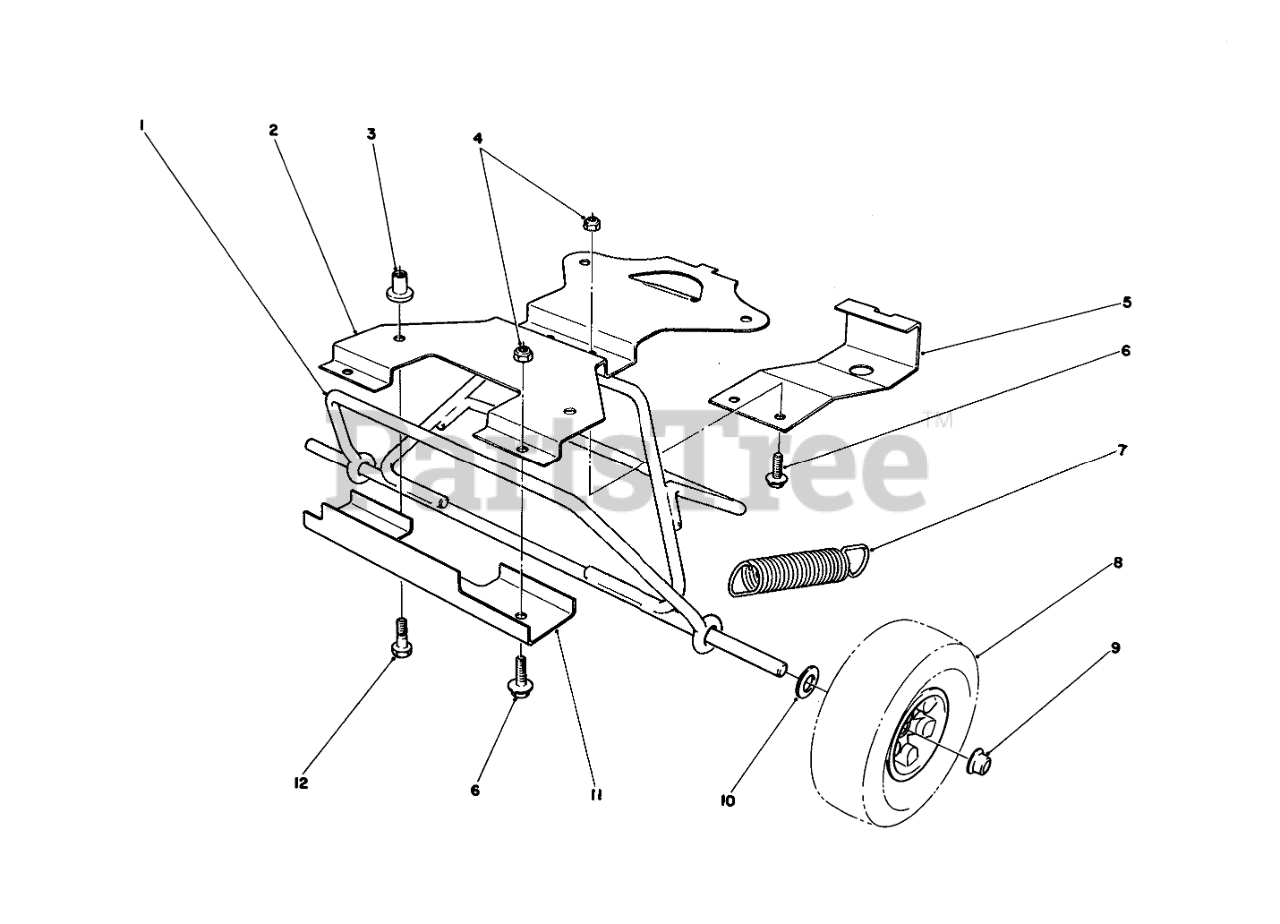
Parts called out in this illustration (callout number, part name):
1	AXLE WA
2	WHEEL PLATE
3	WELLNUT
4	NUT-LOCK, NI
5	COVER
6	SCREW-SHWH
7	EXTENSION SPRING
8	S-120 WHEEL
9	PUSHNUT-CAP, WASHER
10	WASHER-PLAIN
11	AXLE RETAINER
12	MTG SCREW
